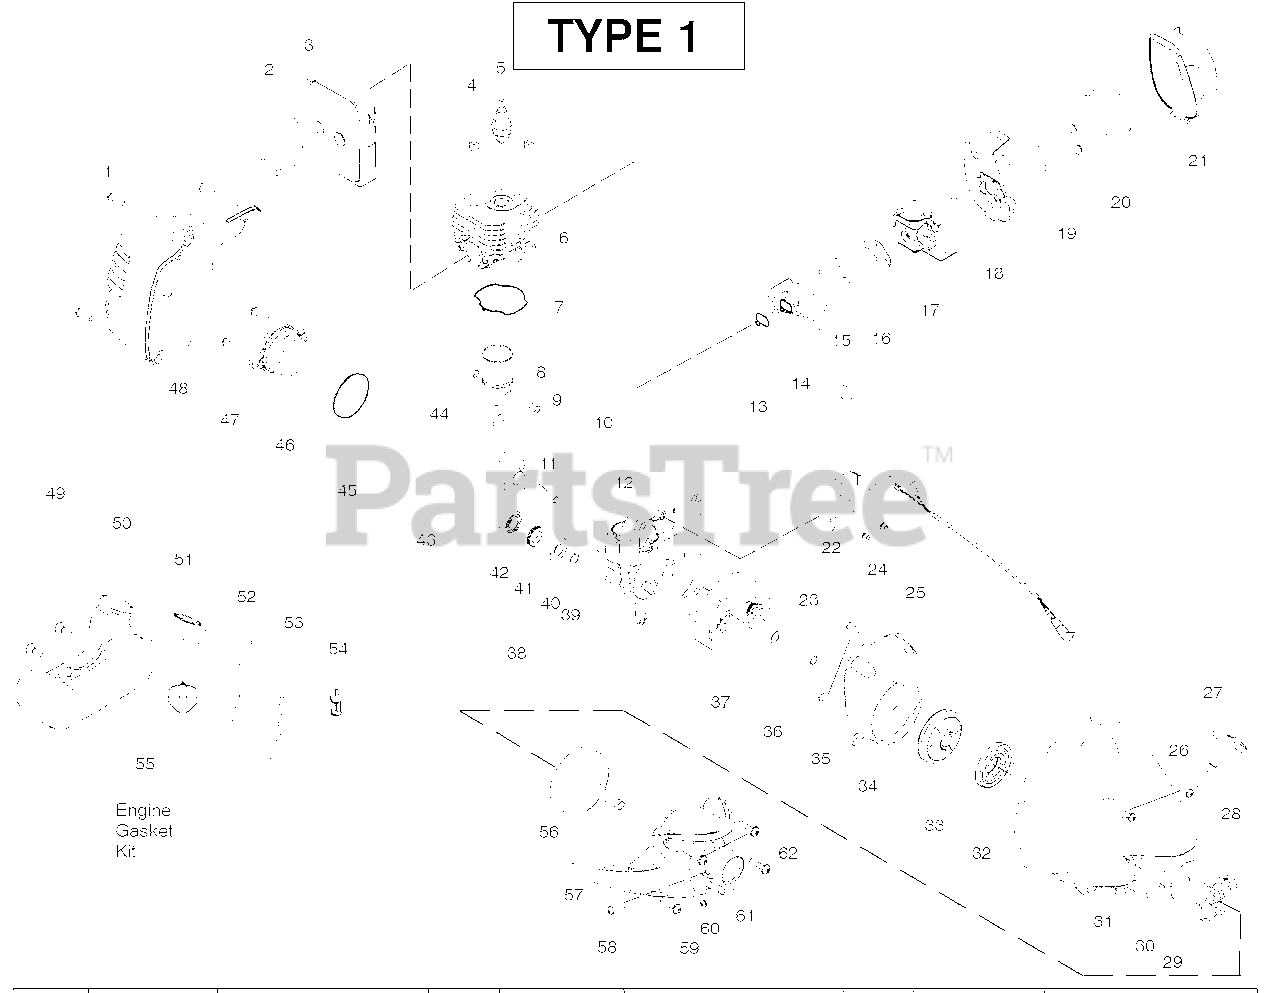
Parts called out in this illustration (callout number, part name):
2	Bolt-Muffler
3	Assy-Muffler/Shield
4	Screw-Cylinder
5	Spark Plug (RCJ 6Y)
6	Cylinder
7	Seal-Cylinder (kit)
8	Piston Ring
9	Retainer-Piston Pin
10	Kit - Piston
11	Assy-Crankshaft
12	Assy-Crankcase
13	Seal-Cyl/Carb.(kit)
14	Adapter-Carb.
16	Gasket-Carb. (kit)
17	Kit-Carb.(C1U-W19)
20	Foam-Air Filter
21	Cover-Air Box
22	Ignition Module
23	Spacer-Flywheel
25	Assy-Switch wire
27	Handle-Starter
28	Kit - Rope
29	Assy-Clutch
30	Washer-Clutch
31	Assy.-Fan Hsg
32	Spring-Starter
33	Kit-Starter Pulley
36	Washer-Clutch Flat
37	Assy-Flywheel
38	Assy-C'case & C'shaft
39	Retain. Ring-C'shaft
40	Outer Bearing
41	Seal-C'shaft
42	Inner Bearing
43	Kit-piston/rod
44	Kit-Conn. Rod
45	O-Ring-C'case (kit)
46	Assy-Plug
48	Shroud-Rear
49	Retainer-Tank
50	Assy-Fuel Tank
51	Assy-Fuel Cap
52	Kit-Fuel Line (Small)
53	Kit-Fuel Line (Large)
54	Assy-Fuel Pickup
55	Kit-Engine Gasket
56	Assy-Clutch Drum
57	Assy-Clutch Cover
58	Screw-Align
60	Screw 12-24
61	Nut 12-24
